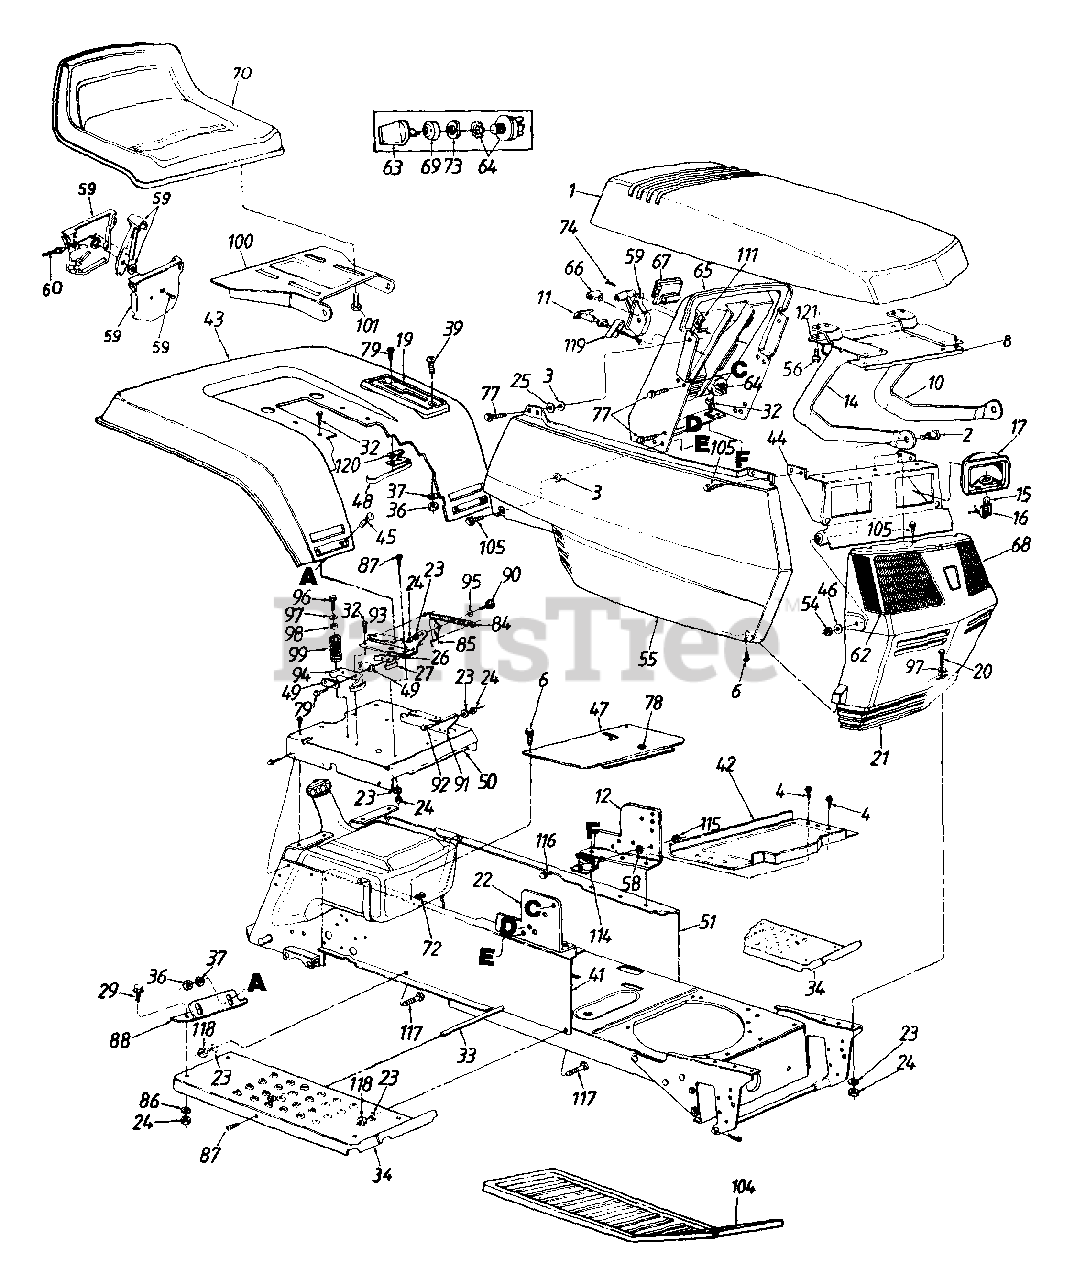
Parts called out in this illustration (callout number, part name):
3	Bolt Retainer 1/4" I.D.
4	Hex AB-Tap Scr. 1/4 x .62" Lg.
6	Truss Mach. B-Tap Scr. #10 x .5" Lg.
8	Hood Reincement
10	Hood Hinge - L.H.
11	Choke Control
12	Dash Support Brkt.- L.H.
14	Hood Hinge - R.H.
15	Lamp
16	Twist Lock - Lamp Socket
17	Headlight Housing
19	Speed Control Index Brkt.
20	Hex Bolt 5/16-18 x .75" Lg.
21	Grille
22	Dash Support Bracket - R.H.
23	L-Wash. 5/16" I.D.
24	Hex Nut 5/16-18 Thd.
25	Fl-Wash. 1/4" I.D. x .93" O.D.
26	Insulator Boss Plate
27	Seat Spring Switch
29	Hex Bolt 5/16-18 x 1.0" Lg.
32	Hex Wash. Hd. AB-Tap Scr. 5/16 x .75" Lg.
33	Running Board Rod
37	L-Wash. 1/4" I.D.
39	Truss Mach. Scr. 1/4-20 x 1.0" Lg.
41	R.H. Side Frame
42	Battery Plate
46	Fl-Wash..328" I.D. x .68" O.D.
49	Insulator Plate
54	Hex Cent. L-Nut 5/16-18 Thd.
55	Side Panel Ass'y. - R.H.
56	Hex Wash. Hd. B-Tap Scr. 1/4 x .62" Lg.
58	Ext. L-Wash. 1/4" I.D.
59	Throttle Control Box Ass'y.
60	Throttle Control Wire 35" Lg.
62	Lens - R.H.
63	Ignition Key
64	Ignition Switch
65	Dash Panel
66	Light Switch
67	Ammeter
68	Lens - L.H.
69	Ignition Switch Cap
70	Seat Ass'y.
72	Speed Nut #10Z
73	Ignition Switch Nut
74	Truss Mach. AB-Tap Scr. #10 x .5" Lg.
77	Hex Wash. Hd. Tap Scr. 1/4 x .75" Lg.
78	Snap Bushing
79	Hex Wash. Hd. AB-Tap Scr. #8 x .50" Lg.
84	Ext. Spring 5.31" Lg.
85	Seat Lift Brkt.
86	Bell-Wash. .345" I.D. x .88" O.D.
87	Truss Machine Scr. 5/16-18 x .75" Lg.
95	Spr.-Wash. .445" I.D.
96	Hex Wash. Hd. Tap Scr. 5/16-18 x .75" Lg.
97	Fl-Wash. .344" I.D. x 1" O.D.
98	Bushing
99	Compression Spring
101	Hex Tap Scr. 3/8-16 x .75"
104	Foot Pad
105	Hex Tap Scr. 1/4-20 x .5" Lg.
111	Speed Nut 1/4-20 Thd.
114	Solenoid
115	Hex Sems Nut 1/4-20 Thd.
116	Hex Bolt 1/4-20 x .5" Lg.
117	Rib Neck Bolt 5/16-24 x .75" Lg.
118	Hex Nut 5/16-24 Thd.
119	Retainer Clip
120	Insulator Nut Plate
